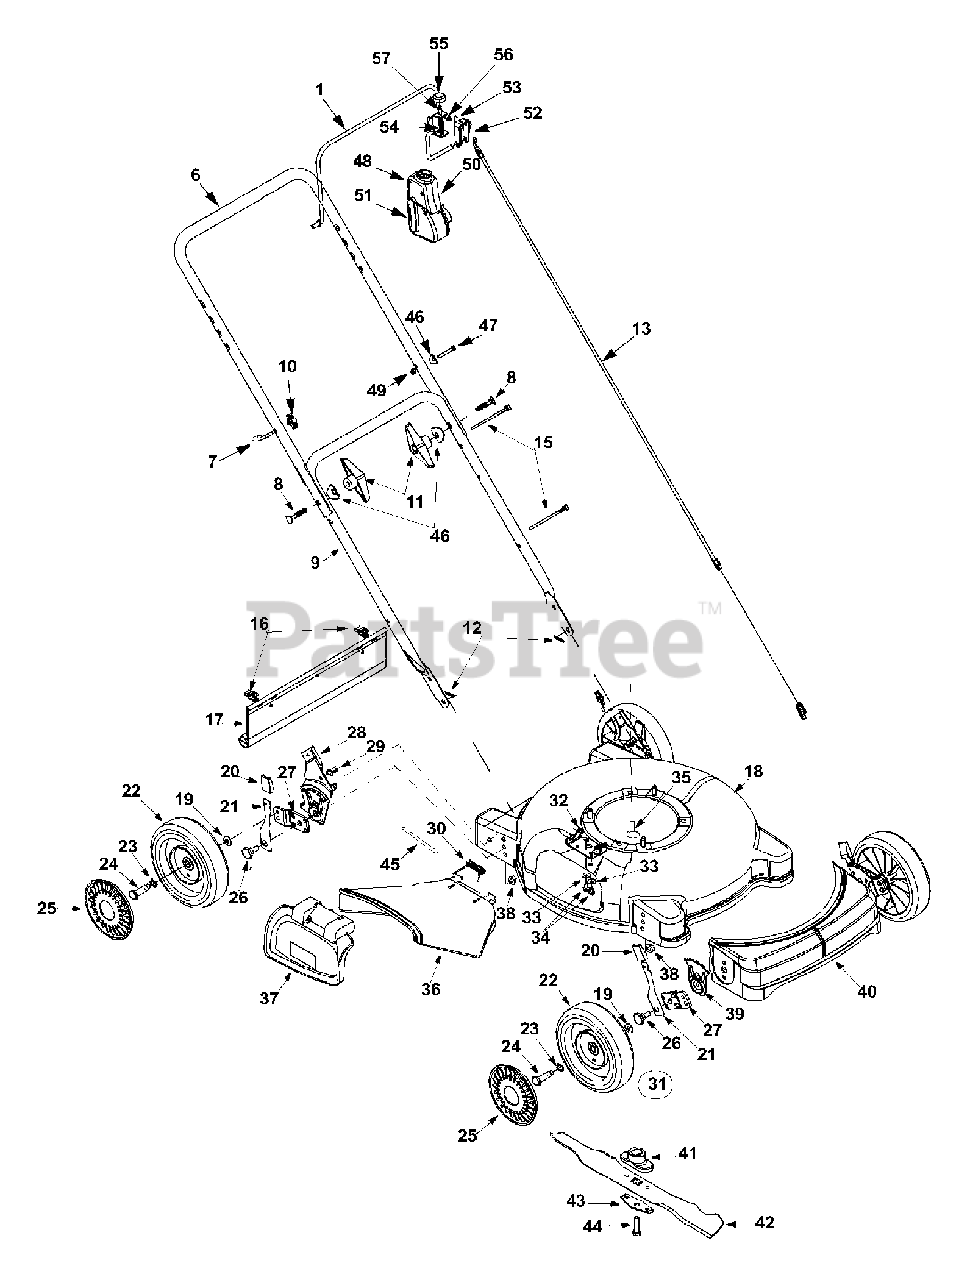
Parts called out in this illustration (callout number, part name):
8	Carriage Bolt
10	Wing Nut
11	Hand Knob
12	Hairpin Clip
13	Control Cable 56.75"
15	Cable Tie
16	Hinge Clip
17	Trail Shield
20	Knob: Height Adjustment
21	Lever: Spring
22	Wheel Assembly
23	Wave Washer
24	Axle Bolt
25	Hubcap: Radial Spoke, Yellow
26	Shoulder Bolt
29	Stake Bolt
30	Torsion Spring
31	Height Adjust. Assembly RH
33	Bell Washer
34	Hex Washer Hd. TT Screw
35	TT Sems Screw
36	Chute Deflector
37	Mulching Plug Assembly
38	Hex Lock Nut
39	Height Adjustment Plate
40	Cover: Front End
41	Blade Adapter
42	20" Mulching Blade
43	Blade Bell Support
44	Hex Bolt
45	Hinge Pin
46	Saddle Washer
47	Hex Hd. Cap Screw
48	Hi-Low Scr. 1/4-20
49	Hex Lock Nut 1/4-20 Gr. 8
50	Control Cover LH
51	Control Cover RH
52	Lever
53	Torsion Spring
54	Compression Spring
55	Button
56	Retention Spring
